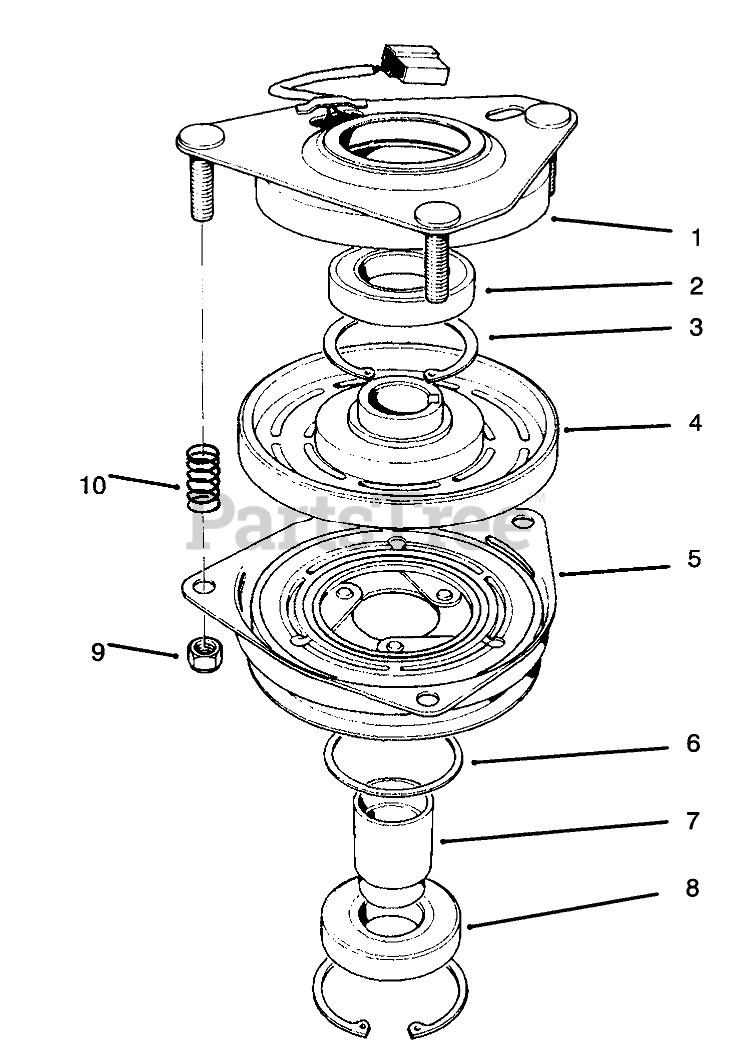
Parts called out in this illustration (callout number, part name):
1	Field Ass-y (Incl. Ref. #2 & 3)
2	BEARING-FIELD
3	RING-RETAINING
4	Field Coil, Rotor & Bearing Assembly (Incl. Ref. #1)
5	Armature & Pulley Assembly (Incl. Ref. #3, 6, 7, & 8)
6	SPACER-BEARING, PULLEY
7	COLLAR-BEARING
8	BEARING-PULLEY
9	NUT-HEX
10	SPRING
